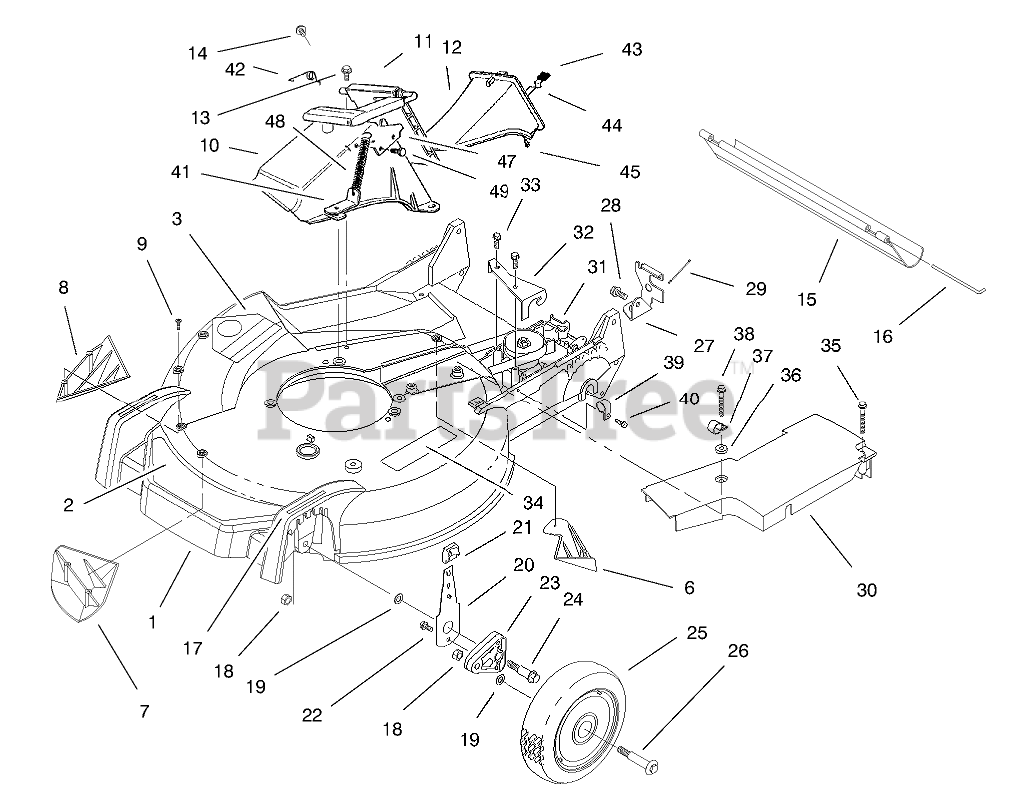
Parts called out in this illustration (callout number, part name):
1	Housing-21" (Incl. Ref. #3, 6-9, & 17 pg. 1 & 34 pg. 2)
2	DECAL - DECK
3	DECAL-DANGER
6	KICKER-REAR
7	KICKER-FRONT
8	KICKER-RH
9	SCREW-PPH
10	TUNNEL-DISCHARGE
11	DISCHARGE DOOR ASM
12	Plug-Discharge (Incl. Ref. #43-45)
13	SCREW-HWH
14	SCREW AND WASHER ASM
15	SHIELD-TRAILING
16	ROD-SHIELD
17	DECAL - HOC
18	NUT-LOCK
19	WASHER
20	FRONT SPRING ARM ASM
21	KNOB-ARM
22	SCREW-HWH
23	ARM-PIVOT, FRONT
24	BOLT-SHOULDER
25	WHEEL AND TIRE ASM
26	BOLT-WHEEL
27	Bracket-Adj. Trac
28	SCREW-HWHTF
29	RETAINER-CABLE
30	COVER - BELT
31	GEARCASE ASM
32	Bracket-Guide
33	SCREW-HWHTF
34	DECAL-WARNING
35	SCREW-HHFTF
36	WASHER
37	CLAMP-CABLE
38	SCREW-SPECIAL
39	CLAMP-CABLE
40	SCREW-HWH
41	BRACKET-SPRING
42	RETAINER-DOOR
43	GRIP-LATCH
44	LATCH-PLUG, DISCHARGE
45	RIVET-HEAD, FLAT
47	LATCH-PLATE
48	SPRING-DOOR
49	SCREW-PLASTITE
